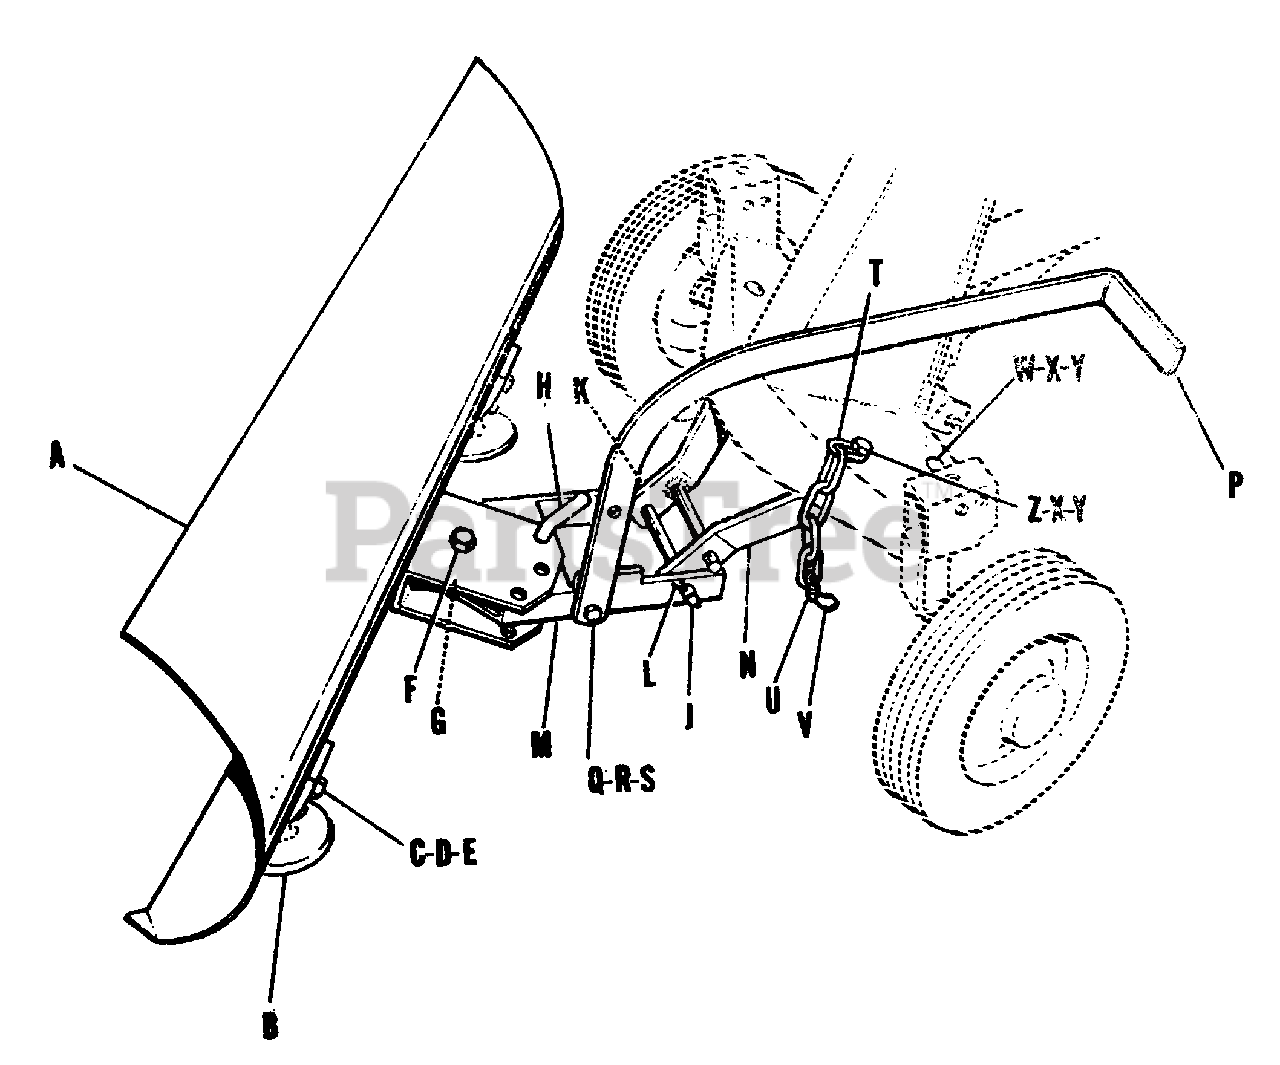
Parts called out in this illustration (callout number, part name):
A	Blade Assembly, 30"
B	Shoe Assembly
C	Carriage Bolt, 3/8-16 x 1
D	LockWasher, 3/8"
E	Hex Nut, Full, 3/8-16
F	Pivot Pin (Vertical)
G	Cotter Pln, 5/32" x 1"
J	Pivot Pin, (Horizontal)
K	Spring Clip
L	Cotter Pin, 5/32" x 1"
M	Push Bar Assembly
N	Blade Hitch Assembly
P	Foot Lever Assembly
Q	Capscrew, Hex, 3/8-16 x 1 1/4
R	LockWasher, 3/8"
T	Foot Lever Chain
V	Spring Clip
W	Carriage Bolt, 3/8-16 x 1"
X	LockWasher, 3/8"
Y	Hex Nut, Full, 3/8-16
Z	Capscrew, Hex, 3/8-16 x 1 1/4
